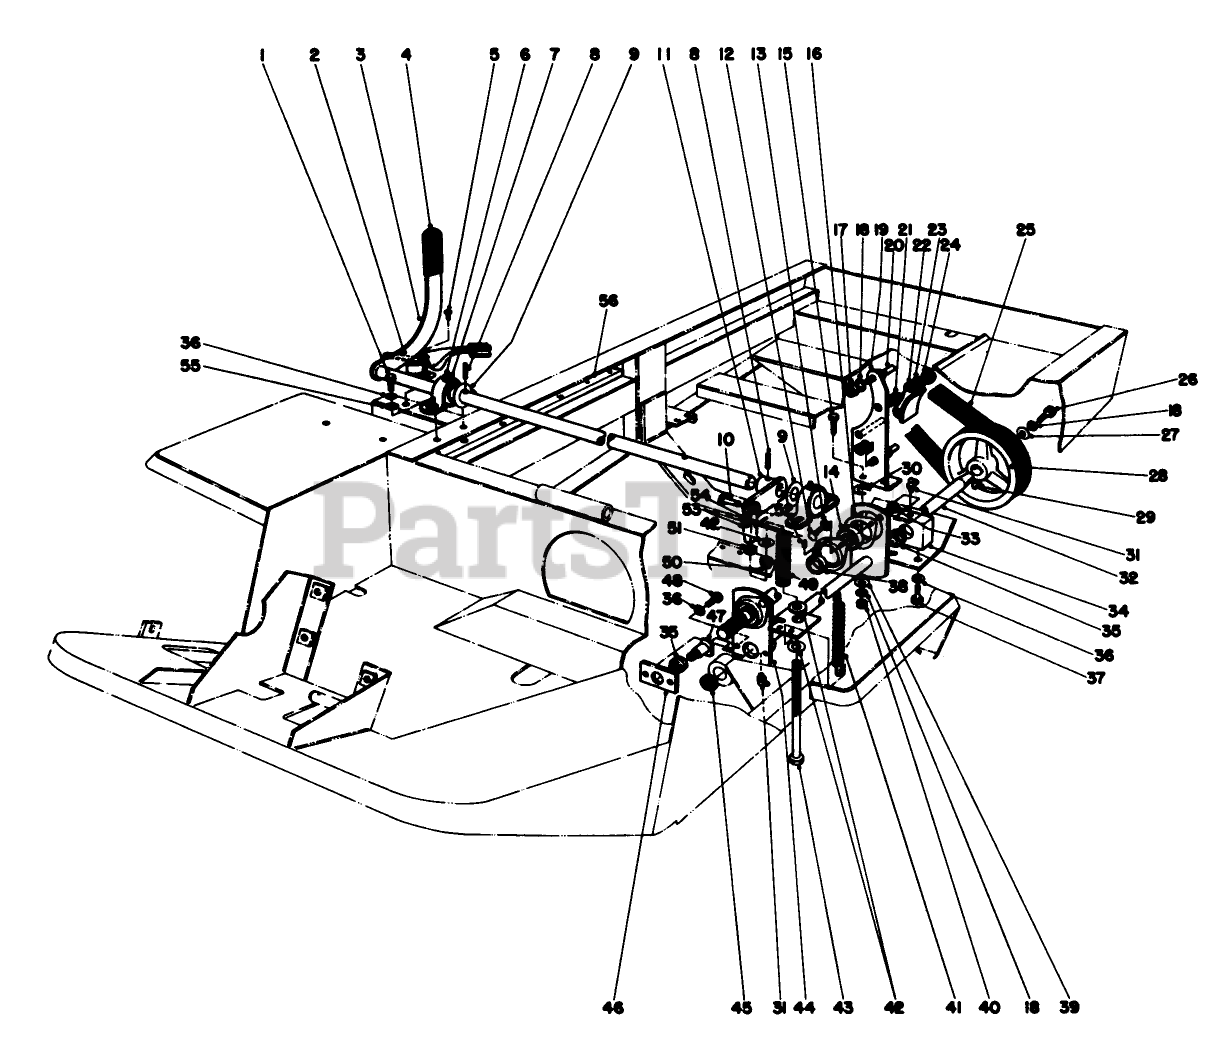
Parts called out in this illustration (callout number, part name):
1	Bolt
2	PTO SWITCH
3	P.T.O. Lever
4	GRIP-HANDLE
5	SCREW-THD FRM,HWH
6	FITTING-GREASE
7	BEARING
8	PIN-SPRING
9	THRUST WASHER
10	PIN-CLEVIS
11	ENGAGE ARM WA
12	SCREW-CARR
13	WASHER-LOCK
14	Bearing w/collar (Incl. Ref. #38 & 52)
15	SCREW-HH
16	FLANGE
17	NUT-JAM
18	WASHER-LOCK
19	PTO BRAKE BRKT WA BO
20	PTO BELT GUIDE
21	COMP SPRING O
22	PTO BRAKE SHOE/LINING
23	WASHER-FLAT
24	NUT-LOCK, NI
25	V-Belt A-Section
26	SCREW-HH
27	WASHER-FLAT
28	PULLEY-PTO, MACH.
29	KEY-WOODRUFF
30	SPECIAL WASHER
31	FITTING-GREASE, 90 DEG
32	PTO SHAFT
33	NUT-HEX
34	BEARING HUB PP
35	BEARING
36	WASHER-LOCK
37	SCREW-HH
38	COLLAR-LOCK, BEARING
39	WASHER-FLAT
40	NUT-HEX
41	TENSION PTO SPRING R
42	WASHER
43	SCREW-ADJUSTING
44	Engagement Arm
45	NUT-LOCK, NI
46	Retainer Bearing
47	Stud Bearing
48	SCREW-HH
49	SPRING-COMPRESSION
50	NUT-HEX
51	NUT-HJ
52	SCREW-SET, HSH
53	Yoke
54	PIN-COTTER
55	WASHER-FLAT
56	Bar Frame Rail
